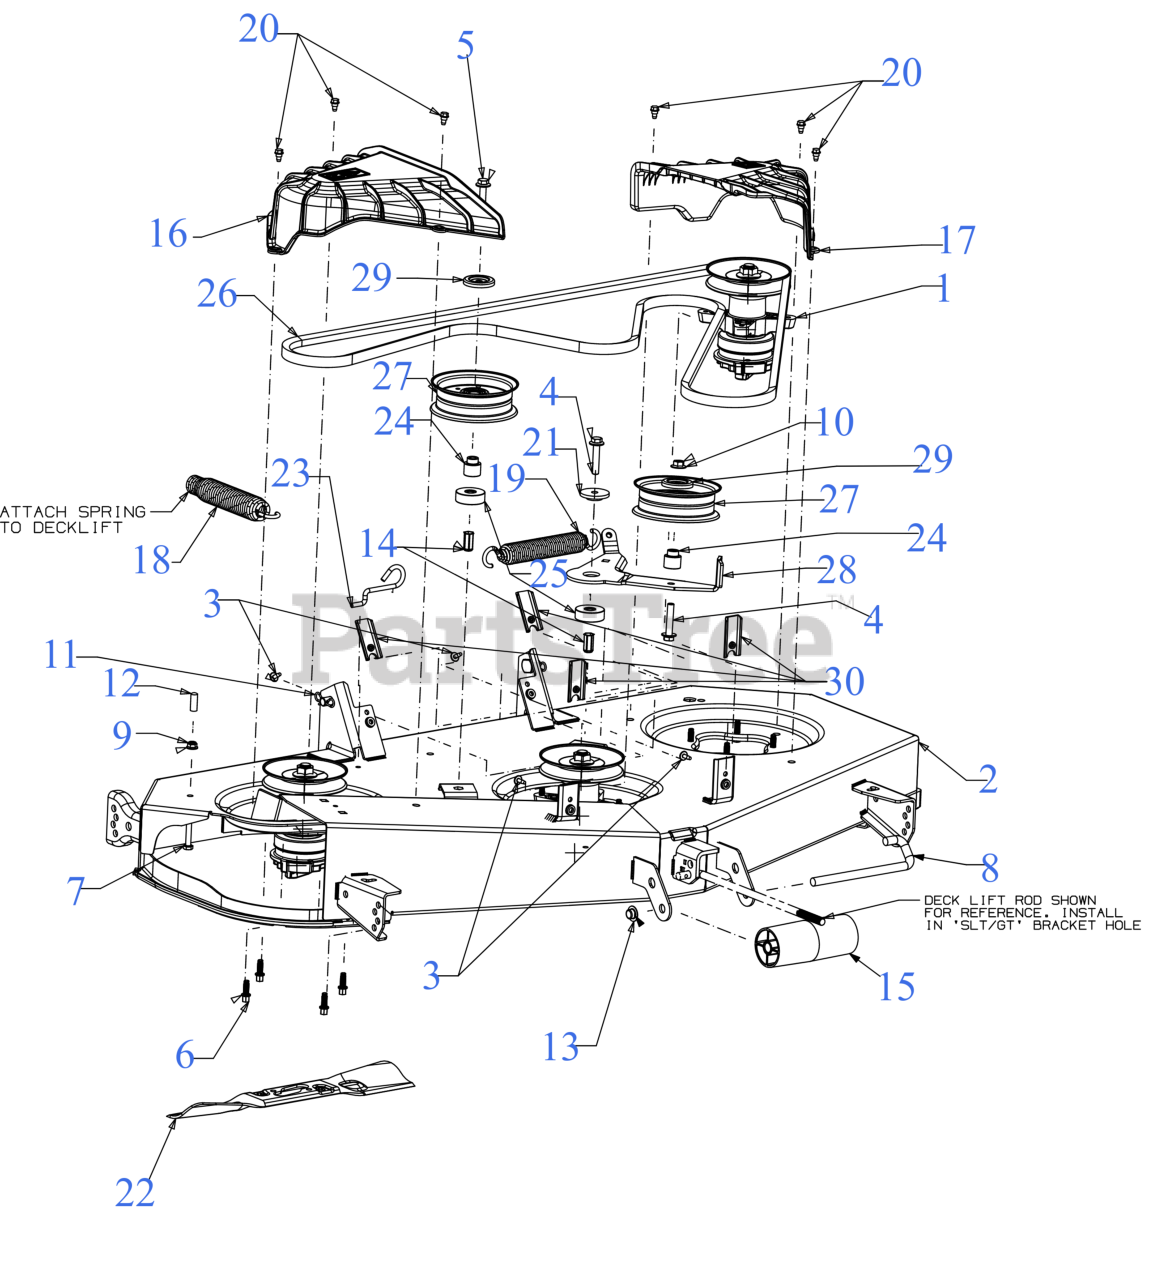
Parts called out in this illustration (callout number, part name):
1	BLADE SPINDLE ASSEMBLY
2	50" FAB DECK SHELL
3	SCREW M6-1 x .625
4	SCREW 3/8-16 x 2.0
5	SCREW 3/8-16 x 2.75 GR5
6	SCREW 5/16-18 x .875
7	SCREW 5/16-18 x 1.5 LG
8	ROLLER PIN 1/2 x 7.31
9	FLANGE LOCK NUT 5/16-18
10	FLANGE LOCK NUT
11	BOW TIE COTTER PIN
14	NUT RIVET 3/8-16
16	SPINDLE COVER (RH)
17	SPINDLE COVER (LH)
18	LIFT ASSIST SPRING (LARGE)
19	SPRING 1.25" DIA x 8.5" LONG
20	SHOULDER SCREW 1/4-20 x .50
21	SHOULDER SPACER
22	50" HIGH-LIFT FASTATTACH BLADE
22	Cub Cadet 50"/54" DETHATCHING BLADE SET
22	50" FASTATTACH XTREME MULCH BLADE
22	50" LOW-LIFT SAND FASTATTACH BLADE
23	DECK SPRING HOOK
24	SHOULDER SPACER
25	SPACER .385ID x 1.75OD x .585THK
26	V-BELT B SEC x 134
26	Cub Cadet 50" DECK BELT
26	Genuine Factory Parts 50" DECK BELT
26	IDLER PULLEY 4.50" DIA
28	IDLER PIVOT BRACKET
29	IDLER PULLEY CAP
